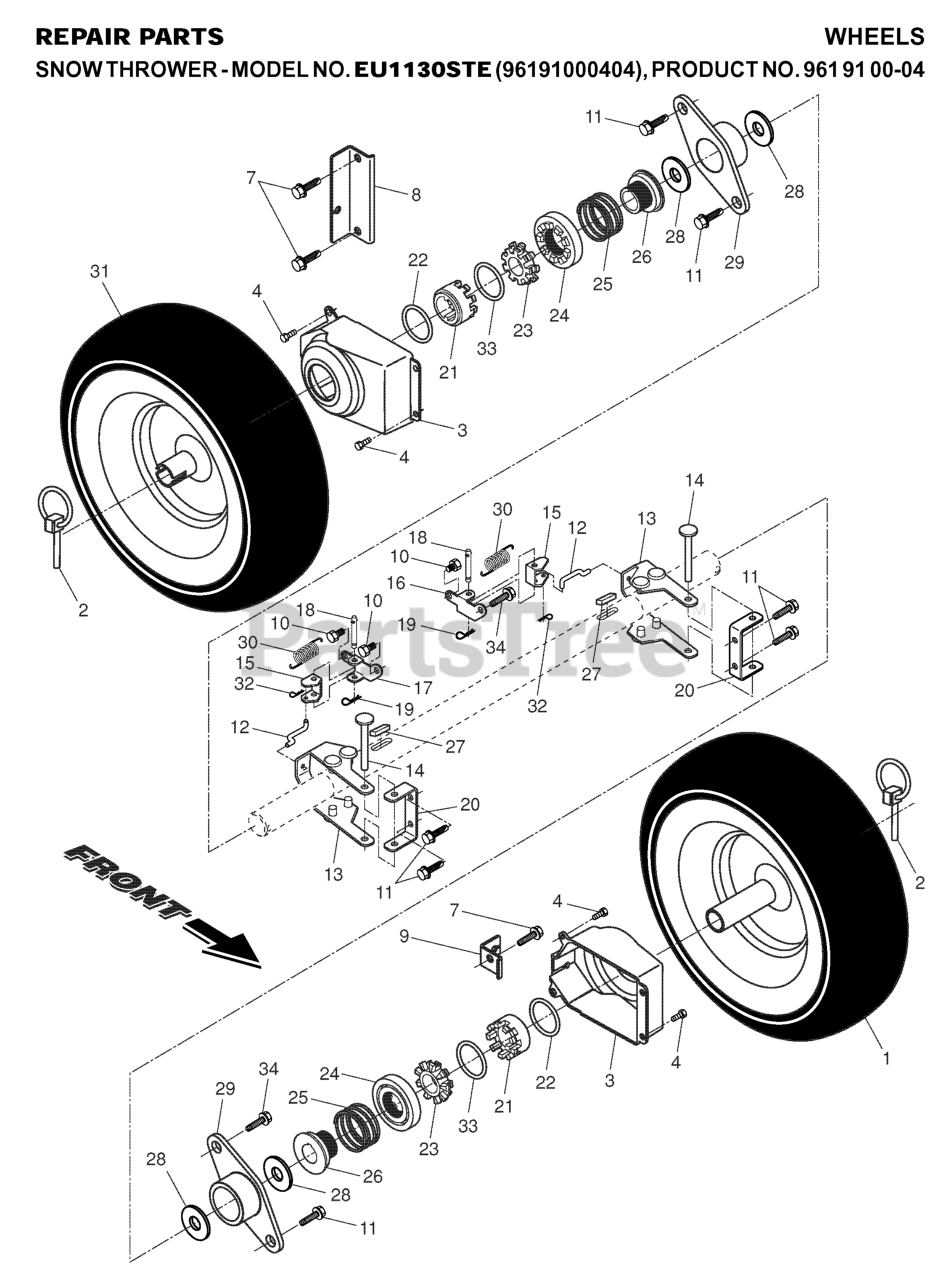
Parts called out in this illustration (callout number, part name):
1	16 X 4.8 LH WHEEL GREY
2	PIN KLIK, 1/4
3	COVER, POWER STEERING
4	SCREW, HEX HEAD, TAPPING
7	SCREW 3/8-16X1
8	BRACKET, STEERING CABLE RH
9	BRACKET, STEERING CABLE LH
10	SCREW 1/4X20
11	SCREW, HEX HEAD 5/16-18 X 1/2
12	LINK, STEERING LEVER
13	YOKE, STEERING
14	PIN, STEERING LEVER
15	BELLCRANK.STEER
16	BRACKET.STEER.PIVOT.LH.YZ
17	BRKT.STEER.PIVOT.RH
18	PIN, STEERING BELLCRANK
19	RETAINER CLIP PM
20	BRACKET.STEER.PNT.BLACK
21	RP.DRIVER WHEEL
22	RING, WIRE RETAINER
23	LOBE WHEEL
24	RP.SLIDE.CLUTCH
25	SPRING, CLUTCH SLIDE
26	RP.LOBE.AXLE
27	KEY, SQUARE 1/4 X .875
28	WASHER TRUST 1"
29	BEARING, AXLE
30	SPRING LATCH
31	16 X 4.8 RH WHEEL
32	RETAINER CLIP
